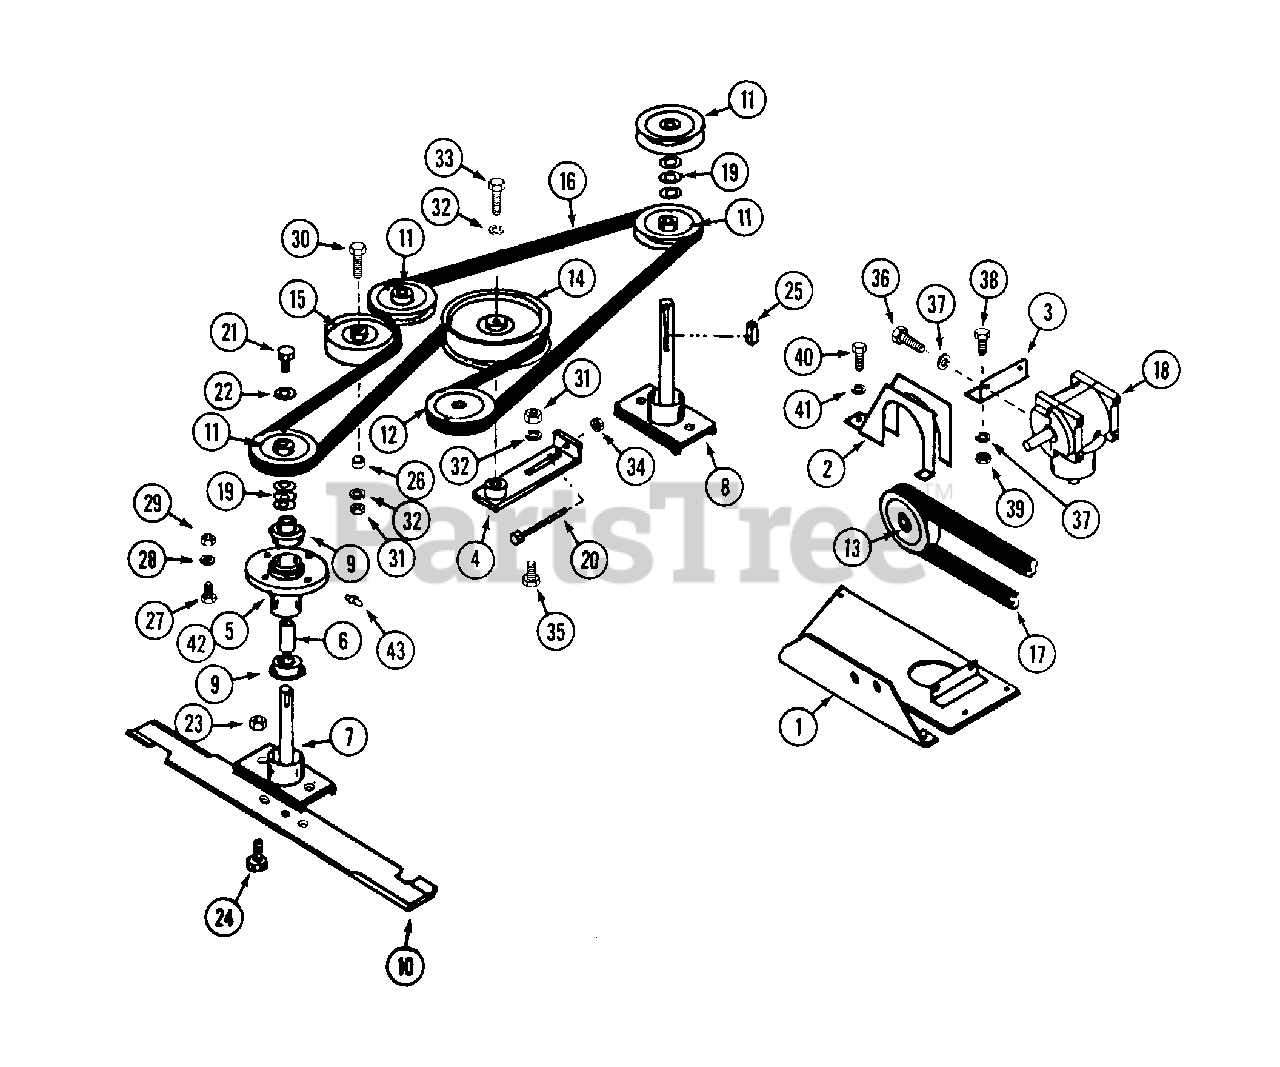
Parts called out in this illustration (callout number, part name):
1	MOUNT - gear box
3	ANGLE - gear box mount
4	TIGHTENER - belt
5	HOUSING - spindle
6	SPACER - spindle
7	SHAFT - spindle
8	SHAFT - spindle, long
9	BEARING - spindle
9	BEARING - spindle 7/8"
10	BLADE - mower
11	PULLEY - spindle
12	PULLEY - gear box output
13	PULLEY - gear box input
14	PULLEY - idler, large
15	PULLEY - idler, small
18	GEAR BOX - angle drive
19	SPACER - washer
20	BOLT - 1/4" - 20 x 4"
21	BOLT - 3/8" - 24 x 1-1/4"
22	WASHER - spindle
23	NUT - 3/8" - 16 lock
24	BOLT - 3/8" - 16 x 1"
25	KEY - 3/16" x 1"
26	SPACER - idler pulley
27	BOLT - 7/16" - 14 x 1-1/4"
28	LOCKWASHER - 7/16"
29	NUT - 7/16" - 14
30	BOLT - 3/8" - 16 x 2-1/2"
31	NUT - 3/8"
32	LOCKWASHER - 3/8"
33	BOLT - 3/8" - 16 x 1-1/4"
34	NUT - 1/4" - 20 lock
35	BOLT - 3/8" - 16 x 1" carriage
36	BOLT - 5/16" - 18 x 1"
37	LOCKWASHER - 5/16"
38	BOLT - 5/16" - 18 x 3/4"
39	NUT - 5/16" - 18
40	BOLT - 1/4" - 20 x 1/2"
41	LOCKWASHER - 1/4"
42	HOUSING ASSEMBLY - spindle
43	FITTING - grease 1/4" - 28
